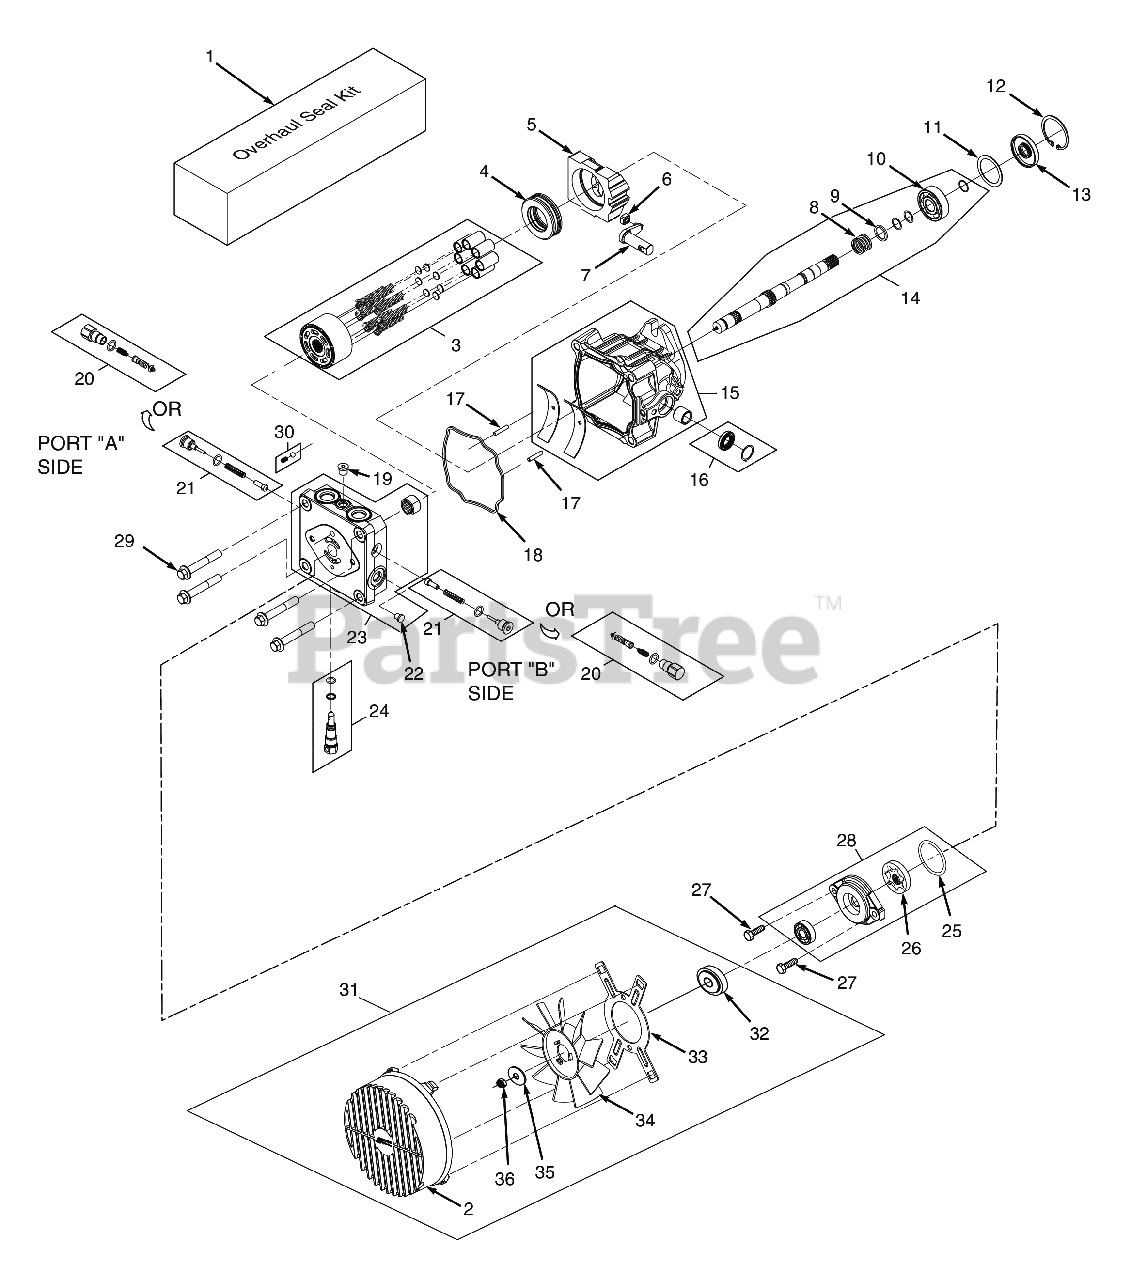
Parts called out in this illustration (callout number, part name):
1	Overhaul Seal Kit
2	Fan Cover
2	Fan Cover w/ Notch (26EFI Right Side Pump Only)
3	Cylinder Block Kit - 16cc
4	Thrust Ball Bearing Assembly
5	Variable Swashplate
6	Slot Guide
7	Trunnion Arm
8	Spring Block
9	Block Thrust Washer
10	Shaft Ball Bearing
12	Retaining Ring
13	Lip Seal
14	Kit, Pump Shaft (keyed thru taper)
15	Housing Kit
16	Trunnion Seal Kit
17	Straight Headless Pin
18	O-Ring
19	Straight Thread Plug
20	System Check Relief Kit, port "B" on Left Hand Pump, port "A" on Right Hand Pump
21	Shock Valve Kit (.024" Orifice)
22	Straight Thread Plug
23	End Cap Kit
24	Bypass Valve Kit
25	O-Ring, Charge Pump Cover
26	Gerotor Assembly (.19 cu.in./rev.)
27	Socket Head Cap Screw (M8 x 1.25-25mm)
28	Charge Pump Kit (.19 STD. Splined)
29	Hex Screw, Flanged Head (M10 x 1.50-65mm)
30	Charge Relief Valve Kit
31	Fan Kit
32	Washer
33	Bracket, Shroud
35	Washer
